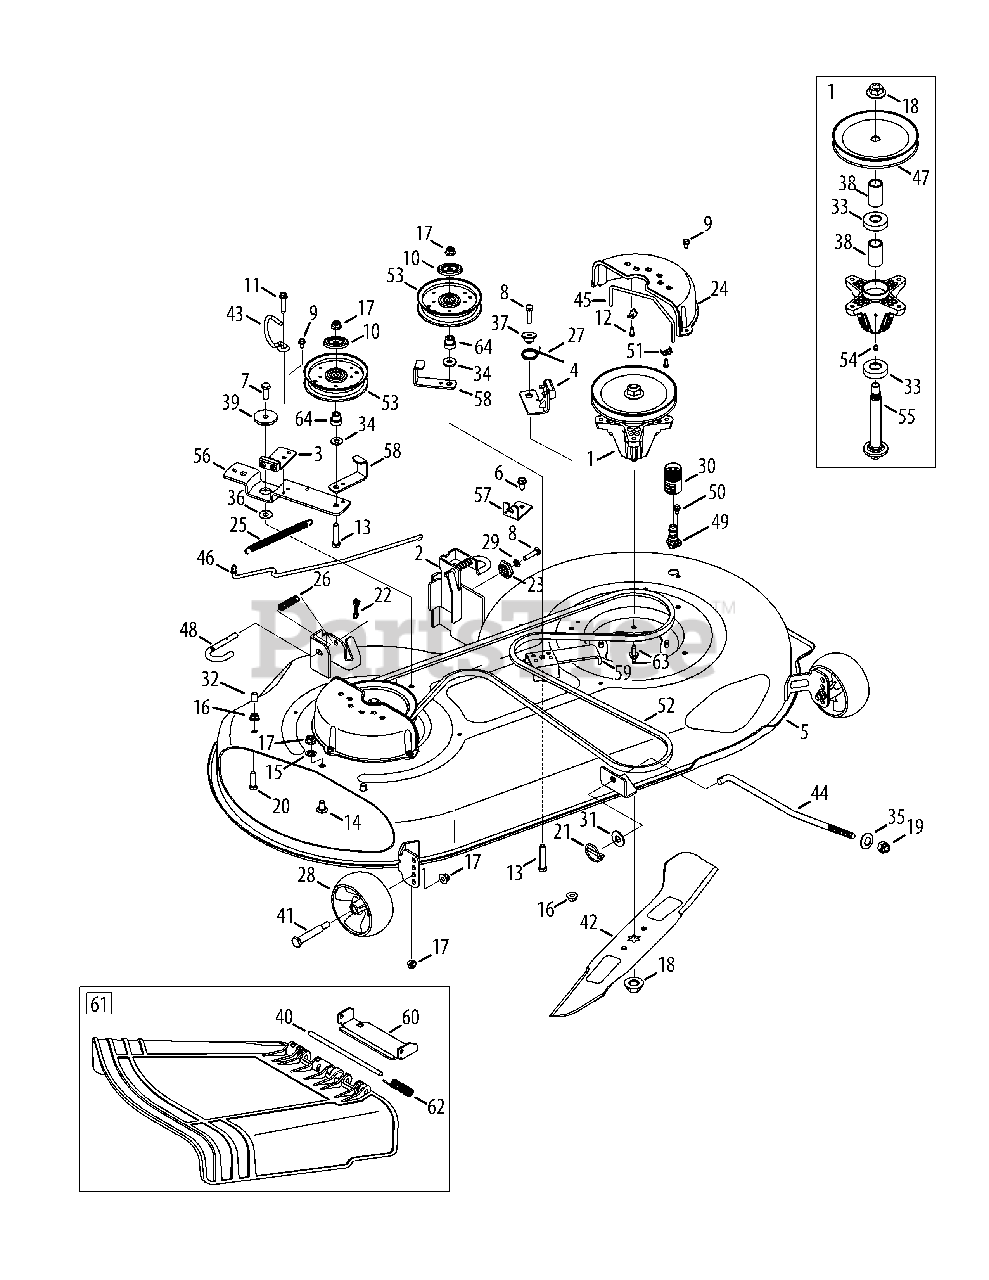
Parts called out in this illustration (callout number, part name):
1	Spindle Ass’y, Pulley, 6.93 Dia
2	Bracket Ass’y, Deck, Hanger LH
3	Brake Ass’y, Deck
4	Brake Ass’y, Deck
5	Deck Shell, Offset, 46" 2W
6	Screw, Self-tapping, 5/16-18, .750,
7	Hex Screw, 3/8-16, 1.00
8	Hex Screw, 5/16-18, 1.25
9	Screw, Self-tapping, 1/4-20, 0.500,
10	Pulley Cap
11	Screw, Self-tapping, 1/4-20, .75,
12	Screw, #10-16 x .625
13	Hex Screw, 3/8-16, 2.00
14	Bolt, Carriage, 3/8-16, 0.75
15	Nut, Push, 3/8
16	Nut, Flange Lock, 5/16-18
17	Nut, Flange Lock, 3/8-16
18	Nut, Flange, 5/8-18
19	Nut, Lock, 1/2-13
20	Hex Cap Screw, 5/16-18 x 1.00
21	Pin, Lynch, .1875
22	Bow-Tie Cotter Pin, 72
23	Gear, Deck, Adjustment
24	Belt Cover
25	Spring, Extension, .62 Dia x 6.12
26	Spring, Comp, .535 OD x 1.751
27	Spring, Torsion, .992 I.D x 1.17 O.D
28	Wheel, Deck, 5.0 Dia Ball
29	Washer, Lock, 5/16, Regular Duty
30	Water Nozzle Adaptor
31	Washer, Flat, .531 x 1.25 x .100
32	Cap, .290 x .500
33	Ball Bearing, .787 ID x 1.85 OD x .551
34	Washer, Flat, .385 x .870 x .092
35	Washer, Bell, .63 x 1.25 x .18
36	Washer, Flat, .385 x 1.0 x .030
37	Spacer, Shoulder, .50 x .145
38	Spacer, .792 x 1.060 x 1.860
39	Spacer, Shoulder, .8840 x .190
41	Bolt, Shoulder, .496 x 2.50, 3/8-16
42	Blade
43	Rod, Keeper, Belt
44	Rod, Lift, Deck, Frt, 13.7
45	Rod, Keeper, Belt
46	Rod, Control, Brake
47	Pulley, Deck, 6.93 Dia
48	Rod, Handle, Deck Release
49	Deck Wash Nozzle
50	Shoulder Screw, 1/4-20 x 0.50
51	Clamp, Casing
52	Belt, V-Type
53	Pulley, Idler, 4.25"Dia
54	Fitting, 3/16, Lnc#70, Drive Lube
55	Shift, Spindle, 6.11.
56	Bracket, Idler, Pivot
57	Bracket, Cable, Deck Engage
58	Bracket, Guard, Belt, 4.25 Pulley
59	Bracket, Support, Deck Stationary Idler
60	Bracket, Chute
61	Chute Ass’y, Deflector
62	Torsion Spring, .44 ID x 2.0
63	Self Tapping Screw, 5/16-18 x .75
64	Shoulder Spacer
